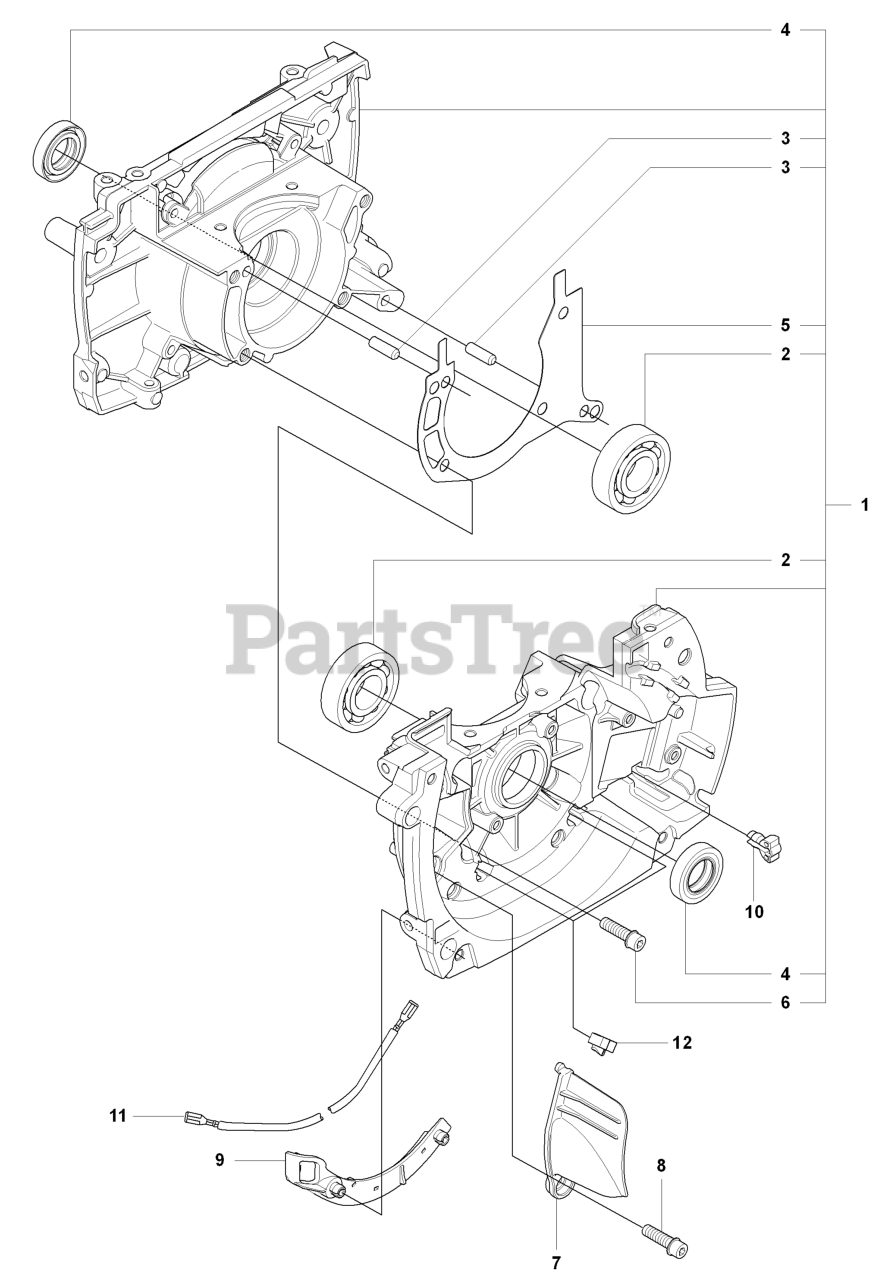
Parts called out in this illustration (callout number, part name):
2	BALL BEARING-6202-C3 SKF
3	PIN 5X14
4	SEALING RING
5	CRANKCASE GASKET
6	SCREW MC6S 5X25
9	CABLE HOLDER
11	SHORT CIRCUIT CABLE
12	GROMMET
